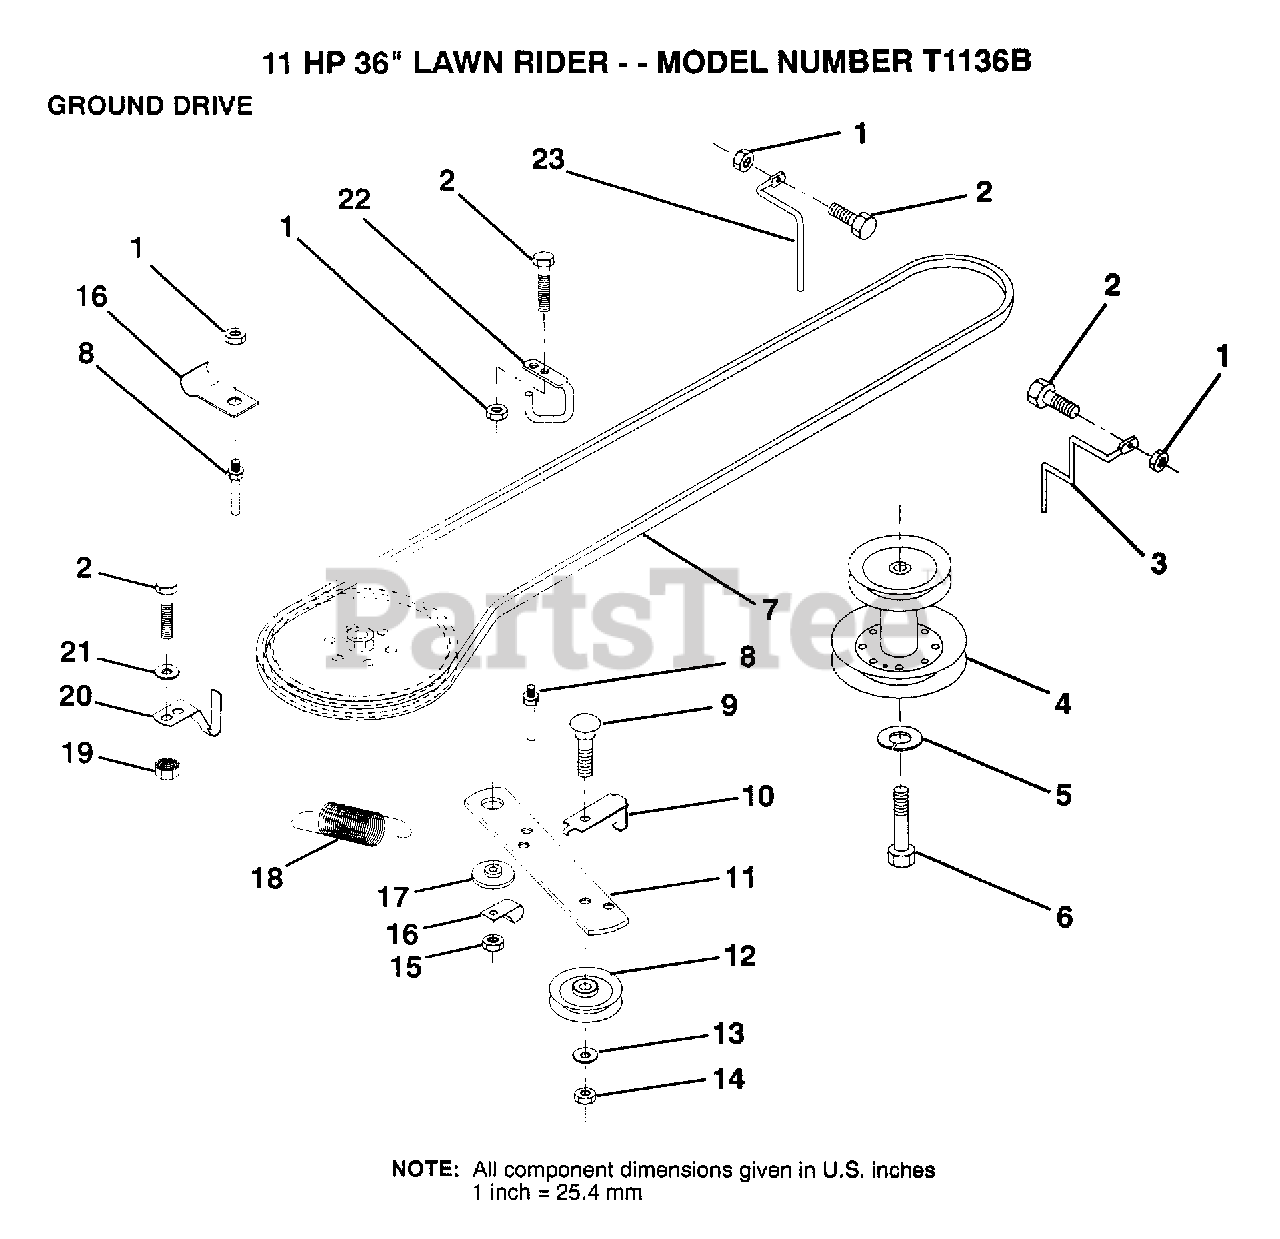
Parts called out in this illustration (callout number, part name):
2	BOLT
5	LOCKWASHER
6	HEX BOLT
7	BELT
8	"KEEPER,DRIVE BELT"
9	BOLT
10	"KEEP,IDLER DR BEL"
13	WASHER
14	LOCKNUT
16	"CLIP,INSULATOR"
17	SPACER RETAINER
20	"KEEPER,DR BELT "
21	WASHER
22	"KEEPER,FRA DR BEL"
